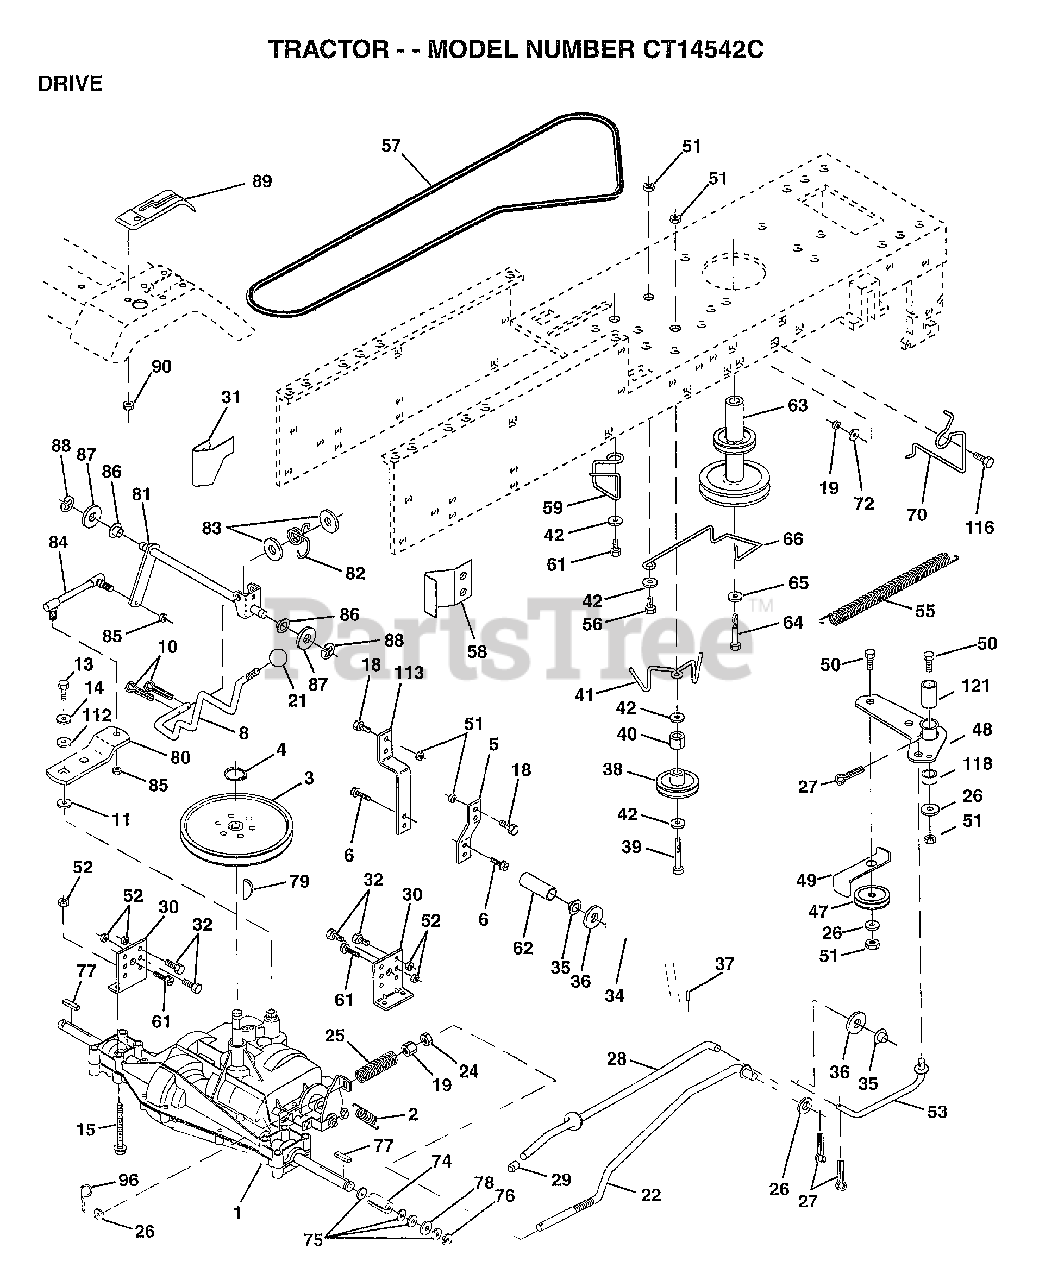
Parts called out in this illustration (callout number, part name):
2	SPRING.BRAKE.RETU
3	PULLEY TRANS
5	SPRING
6	SCREW
8	ROD SHIFT FEND LT
10	PIN COTTER 1/8
11	WASH-SHFT PLT LT
13	BOLT.1/4-28.W/PAT
14	LOCKWASHER
15	BOLT.HX.FLG.5/16
16	WASHER
18	BOLT
19	NUT
21	KNOB T (1/2-HOLE)
22	BRAKE ROD
24	NUT
25	SPRING ROD LT
27	COTTER PIN
28	ROD.BRAKE.PARK.LT
29	PLUNGER CAP T
30	TRANSAXLE MTG BKT
31	"KEEPER,BELT LH T"
32	BOLT
34	SHAFT ASM-PEDAL F
35	NYLON BEARING
36	WASHER LT
38	PULLEY.IDLER.FLAT
39	BOLT
40	SPACER T
42	WASHER
48	BELLCRANK ASM
49	RETAIN BELT
52	NUT
53	"LINK, CLUTCH T"
55	"SPRING, RETURN LT"
58	"KEEPER,BELT RH T"
59	KEEPER BELT CNTSP
61	SCREW
62	PEDAL COVER T
63	PULLEY.ENGINE
64	BOLT
65	LOCKWASHER
66	KEEPER-BELT
70	KEEPER BELT ENG
72	WASHER
74	SPACER, AXLE
75	WASHER
76	E-RING LT
77	SQUARE KEY
78	WASHER
80	"ARM.SHIFT.20""TIRE"
81	SHAFT.CROS.P930.
82	"SPRING,TORSION"
83	WASHER
84	"ROD.TIE.20""P930LT"
85	NUT.CNT.LOCK.1/4
86	BUSHING
87	WASHER D
88	KLIP RING
90	NUT
96	RETAINER M
112	WASHER LT
113	"STRAP,TORQUE"
116	BOLT RDHD 3/8-16
118	SPACER BELLCRANK
121	NYLINER-CLUTCHING
